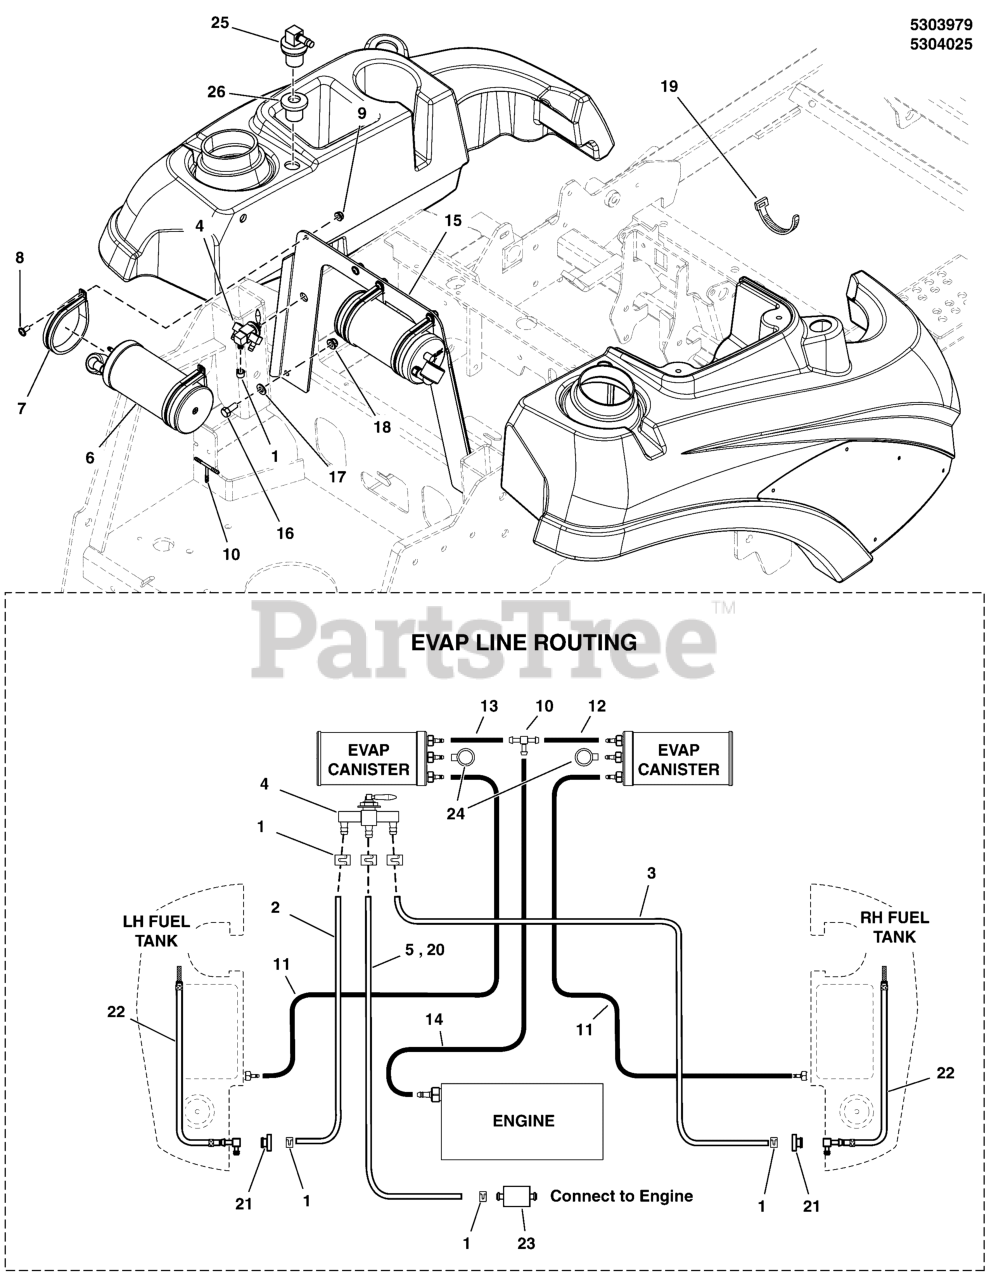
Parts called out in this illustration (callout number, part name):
1	CLAMP, HOSE, EXTERNAL, 1/2 - RED
2	HOSE, 1/4" FUEL, 9.00"
3	HOSE, 1/4" FUEL, 27.00"
4	VALVE, FUEL SHUT-OFF, 12773
5	HOSE, 1/4" FUEL, 19.50"
6	CNSTR, CARB, 6 GAL
7	CLAMP, 3" ID, CUSHIONED, STAINLESS
9	NUT, 1/4-20 HEX NYLOCK FLANGE
10	FITTING, 3/16" TEE, BARB TYPE, HDPE
11	HOSE, VAPOR, 5MM ID, 10.50 LG
12	HOSE, VAPOR, 5MM ID, 18.00 LG
13	HOSE, VAPOR, 5MM ID, 4.50 LG
14	HOSE, VAPOR, 5MM ID, 33.00 LG
15	PLATE, MOUNT, CANISTER, IS2100Z - BLK
16	BOLT, 5/16-18 X 3/4 GD5
17	WASHER, 5/16" SAE
18	NUT, 5/16-18 HEX NYLOCK FLANGE
19	TIE, SELF-LOCKING, 12"
20	HOSE, 1/4" FUEL, 12.00"
21	BUSHING-FUEL TANK RED RUBBER
22	HOSE ASSEMBLY (SV)
23	FUEL FILTER (SV)
24	DUST FILTER, CANISTER (SV)
25	REMOTE VENT ASSEMBLY
26	GROMMET (SV)
